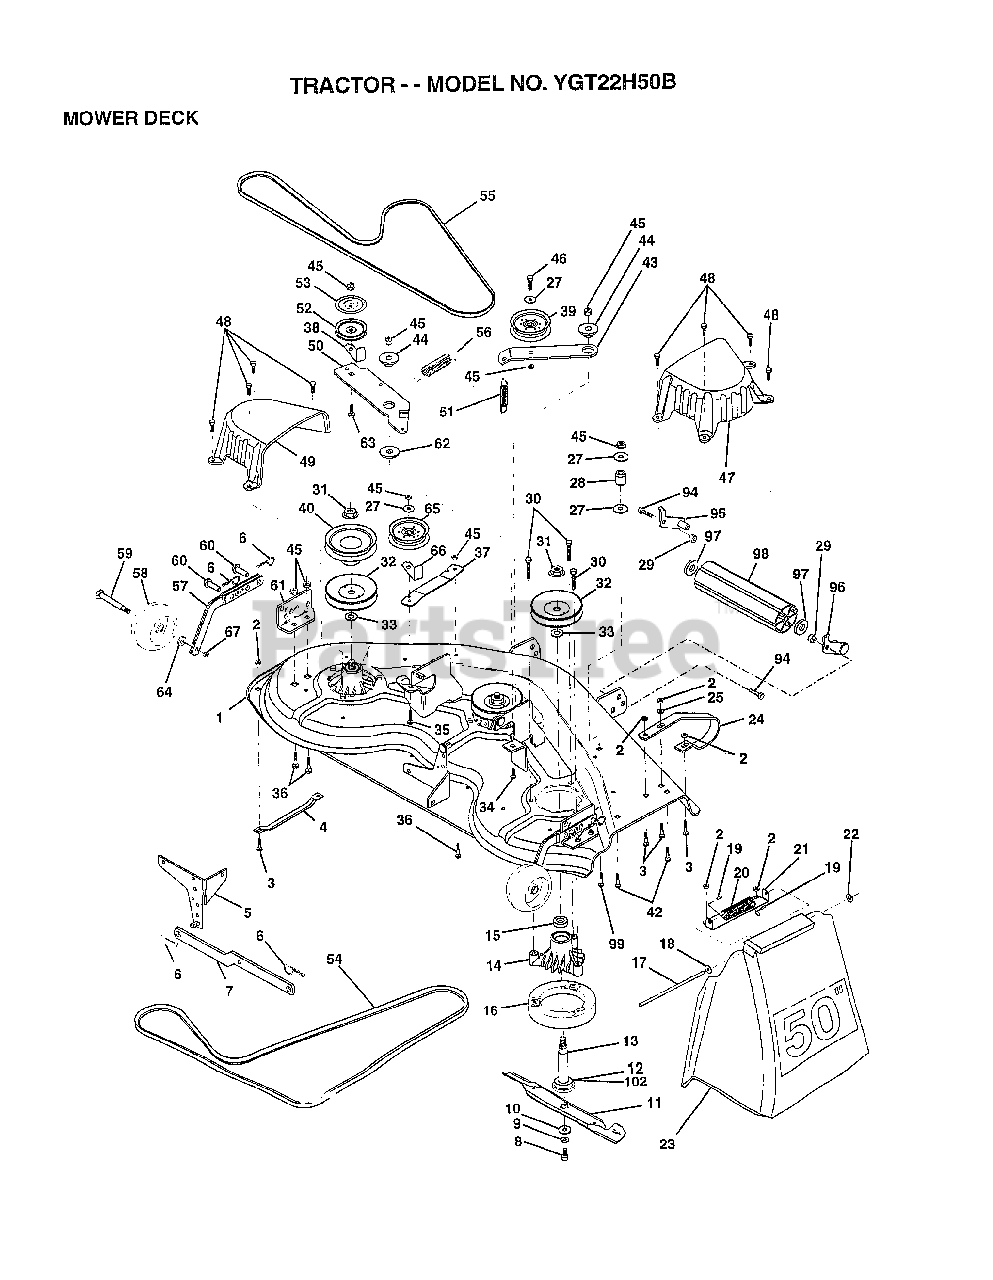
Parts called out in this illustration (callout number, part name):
1	"DECK ASM-50"""
4	RUNNER-LH M
5	BRKT.ASM.SW.44/50
8	BLADE BOLT
10	WASHER.HARD.BLADE
11	"BLADE.50"" HD"
12	BEARING.BALL
13	SHAFT.ASM.W/BRNG
14	HOUSING.MAND.44.V
15	BEARING
16	STRIPPER RND MWR
17	ROD-HINGE T
18	WASHER
20	SPRING TORSION
21	BRKT DEFLECTOR
23	DEFLECTOR
24	"RUNNER RH 50"" DK"
25	WASHER M
27	WASHER
29	NUT
30	"SCREW-THD ROLL,WA"
32	PULLEY.MANDREL.42
33	WASHER
34	BOLT.3/8-14X1.25
35	BOLT
36	BOLT D
37	STIFFENER.ARM.IDL
38	"KEEPER-BELT,IDLER"
39	FLAT IDLER PULLEY
40	"PULLEY.DRIVEN.44"""
42	BOLT
43	"ARM.IDLER.SEC.44"""
44	SPACER RETAINER
47	"COVER.MAND.RH.44"""
48	SCREW.1/4-20X5/8
49	COVER.MANDREL.LH
50	ARM.IDLER.PRIMARY
51	"SPRING.SEC.44""VEN"
52	PULLEY.IDLER.VGRO
53	SHIELD.IDLER.44.V
54	BELT V PRIM 50
55	BELT-V.SEC.46.KEL
56	SPRING.EXT.DECK.
57	BAR.ASM.GUAGE.WHL
58	WHEEL GAGE DONUT
59	BOLT.SHOULDER
60	PIN.CLEVIS
61	BRACKET.GUAGE.WHL
62	HARDENED WASHER
63	BOLT.3/8-16X1.50
64	WASHER
65	PULLEY IDELR FLAT
66	"KEEPER-BELT,IDLER"
67	LOCKNUT
94	BOLT
97	WASHER
99	BOLT
102	WASHER.FELT.
